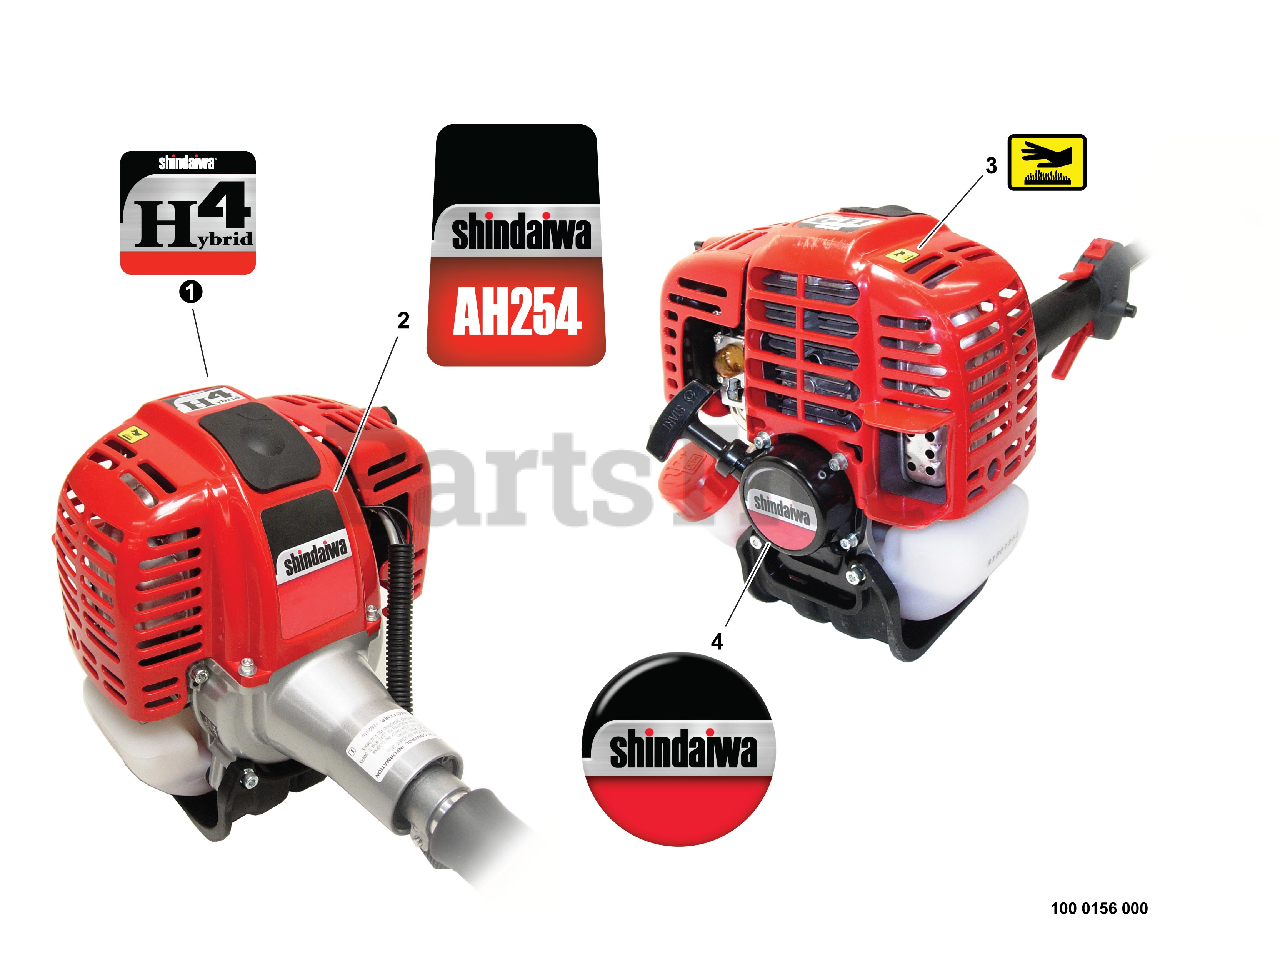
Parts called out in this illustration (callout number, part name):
1	LABEL - H4
2	LABEL - MODEL AH254
3	LABEL - HOT SURFACE
4	LABEL - SHINDAIWA
